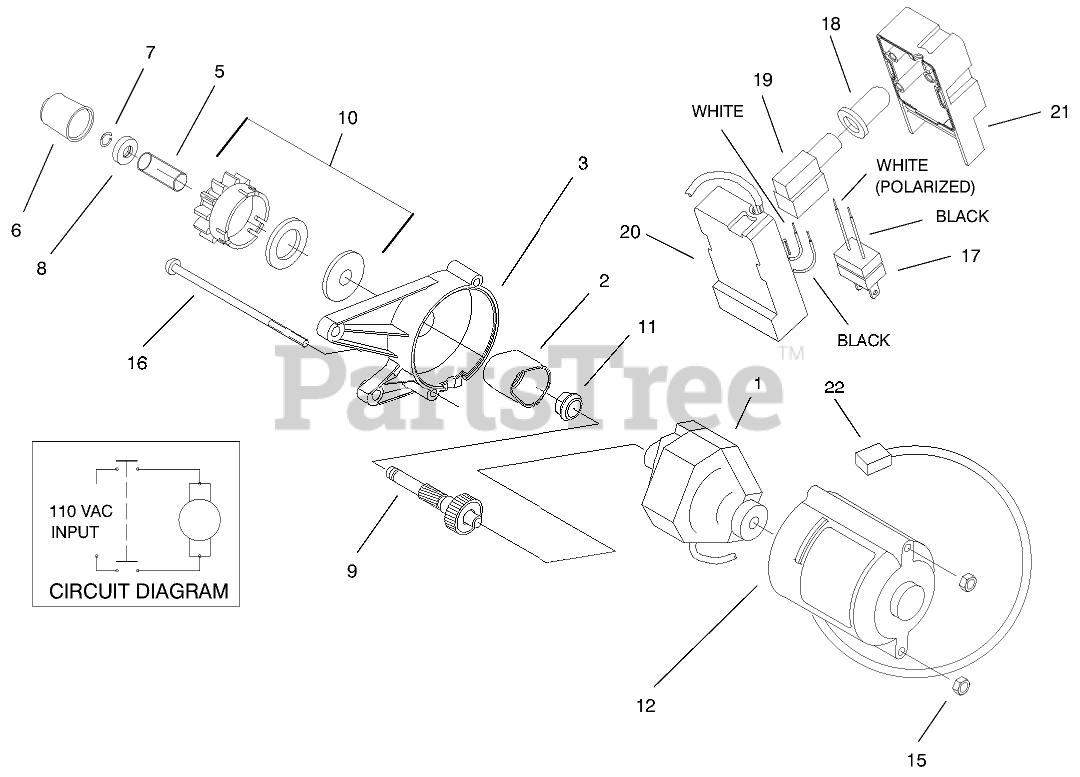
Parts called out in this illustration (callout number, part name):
1	STARTER MOTOR ASM
2	COVER-GEAR
3	Housing-Starter
5	SPRING
6	CAP-PINION
7	RING-LOCK
8	PINION STOP
9	Asm-shaft & Gear
10	PINION ASM
11	BUSHING
12	HOUSING COVER
15	NUT-LOCK, NI
17	PLUG-POWER
18	BOOT-SWITCH
19	SWITCH-STARTER
20	LEVER - ADJUSTING
21	PLATE - COVER
22	TIE-CABLE
